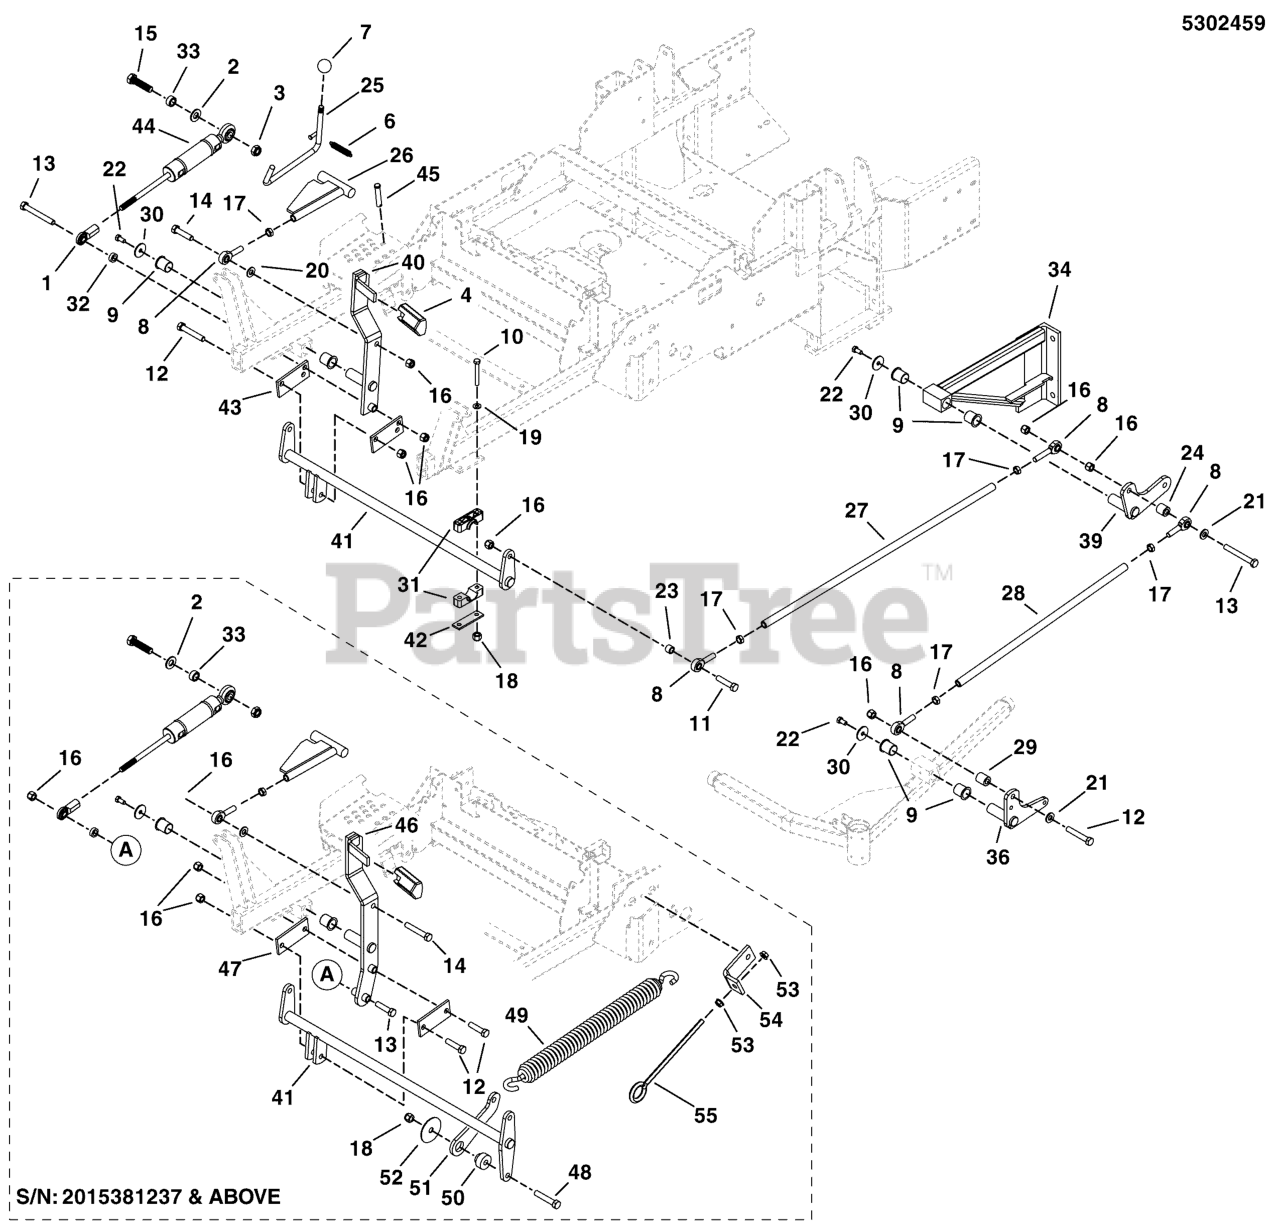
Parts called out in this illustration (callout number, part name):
1	JOINT-BALL .500-20 THD .500ID BLK PLT
2	WASHER, 5/8 SAE
3	NUT, 5/8-11 HEX JAM NYLON LOCK
4	PEDAL, Rubber
5	GREASE FITTING, 1/4-28 STRAIGHT
6	SPRING-EXT, .500 OD X 3.50 LG X .058 WR
7	KNOB, PLASTIC, 1/2-13
8	BALL JOINT, 1/2-20, MALE
9	BUSHING, 1.00 X 1.13 X 1.38, PLASTIC
10	BOLT, 3/8-16 X 2-3/4" GD5 CZ
11	BOLT, 1/2-13 X 2-1/4" GD5 CZ
12	BOLT, 1/2-13 X 3" GD5 CZ
13	BOLT, 1/2-13 X 4" GD5 CZ
14	BOLT, 1/2-13 X 1-1/2 GD5 CZ
15	BOLT, 5/8-11 X 2-1/2 GD5, CZ
16	NUT, 1/2-13 HEX NYLON LOCK
17	NUT, 1/2-20 HEX JAM
18	NUT, 3/8-16 HEX NYLON LOCK
19	WASHER, 3/8 SAE
20	WASHER, 1/2 SAE
21	WASHER, 1/2 GD9 YZ
22	BOLT, 3/8-16 X 3/4, PLT W/PATCH
23	SPACER, .51 X .75 X .56, CZ
24	SPACER, .52 X 1.00 X 1.00
25	WELD, ROD DECK LIFT
26	WELD, DECK ADJUST LINK
27	ROD, DECK LIFT INNER
28	ROD, DECK LIFT OUTER
29	SPACER, .52 X 1.00 X 1.15
30	WASHER, .390 X 1.50 X .109, YZ
31	PIVOT BLOCK, PLASTIC
32	SPACER, .56 X .90 X .31
33	SPACER, .64 X 1.00 X .50, CZ
34	WELD, REAR DECK LIFT, LH
35	WELD, REAR DECK LIFT, RH
36	WELD, DECK LIFT LEVER, LH - BLK
37	WELD, DECK LIFT LEVER, RH - BLK
38	WELD, DECK LIFT LEVER, RH - RED
39	WELD, DECK LIFT LEVER, LH - RED
40	WELD, DECK LIFT PEDAL - RED
41	WELD, DECK LIFT SHAFT, IS5100Z - RED
42	PLATE, PIVOT BLOCK SUPPORT - BLK
43	LINK, DECK LIFT
45	PIN-CLEVIS, 1/2 X 2-1/2 YZP
46	WELD, DECK LIFT PEDAL, IS5100Z
47	LINK, DECK LIFT, IS5100Z
48	BOLT, 3/8-16 X 2, GD5, CZ
49	SPRING-EXT, 1.393 ODX13.25LGX.218WR, BLK
50	BUSHING, DECK PIVOT
51	LINK, SPRING
52	WASHER, .39 X 2.00 X X .14
53	NUT, 3/8-16 HEX
54	ANCHOR, EYEBOLT
55	EYE BOLT, 3/8-16 X 8, 1 EYE
